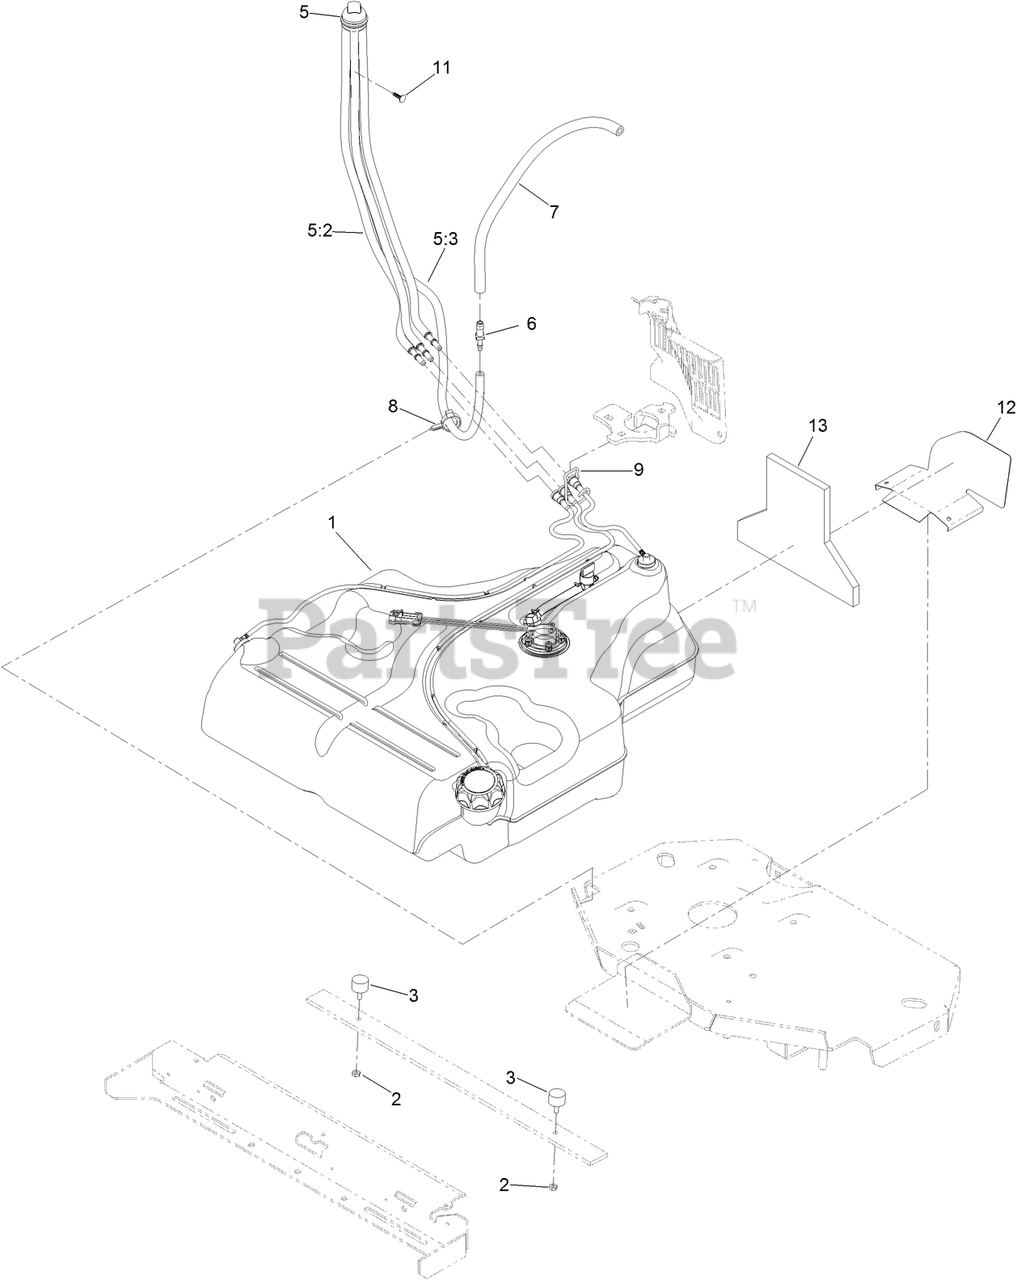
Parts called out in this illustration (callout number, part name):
1	FUEL TANK ASM
2	NUT-JAM
3	BUMPER
5	FUEL MANIFOLD VENT ASM
5:2	HOSE-FUEL
5:3	HOSE-FUEL
6	FITTING-STRAIGHT
7	HOSE-FUEL
8	CLAMP-HOSE
9	RETAINER-LINE, VAPOR
11	PLUG-PLASTIC
12	GUARD-EXHAUST
13	INSULATION-FOAM, FUEL TANK
